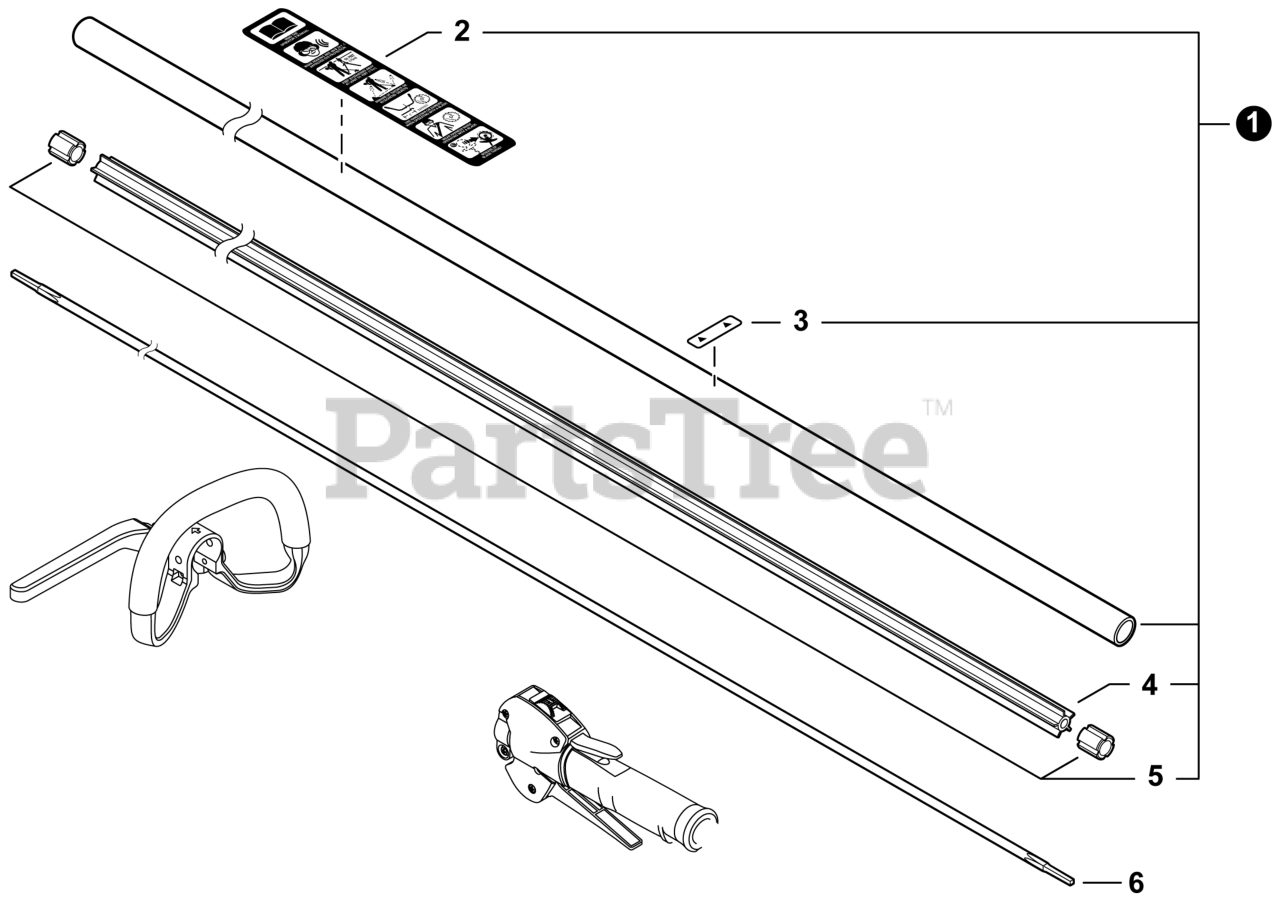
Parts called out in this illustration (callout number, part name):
1	MAIN PIPE ASSY
2	LABEL - CAUTION (BLADE CAPABLE)
3	LABEL - ALIGNMENT
4	LINER, FLEXIBLE 21.6×1420
6	DRIVESHAFT - FLEXIBLE
